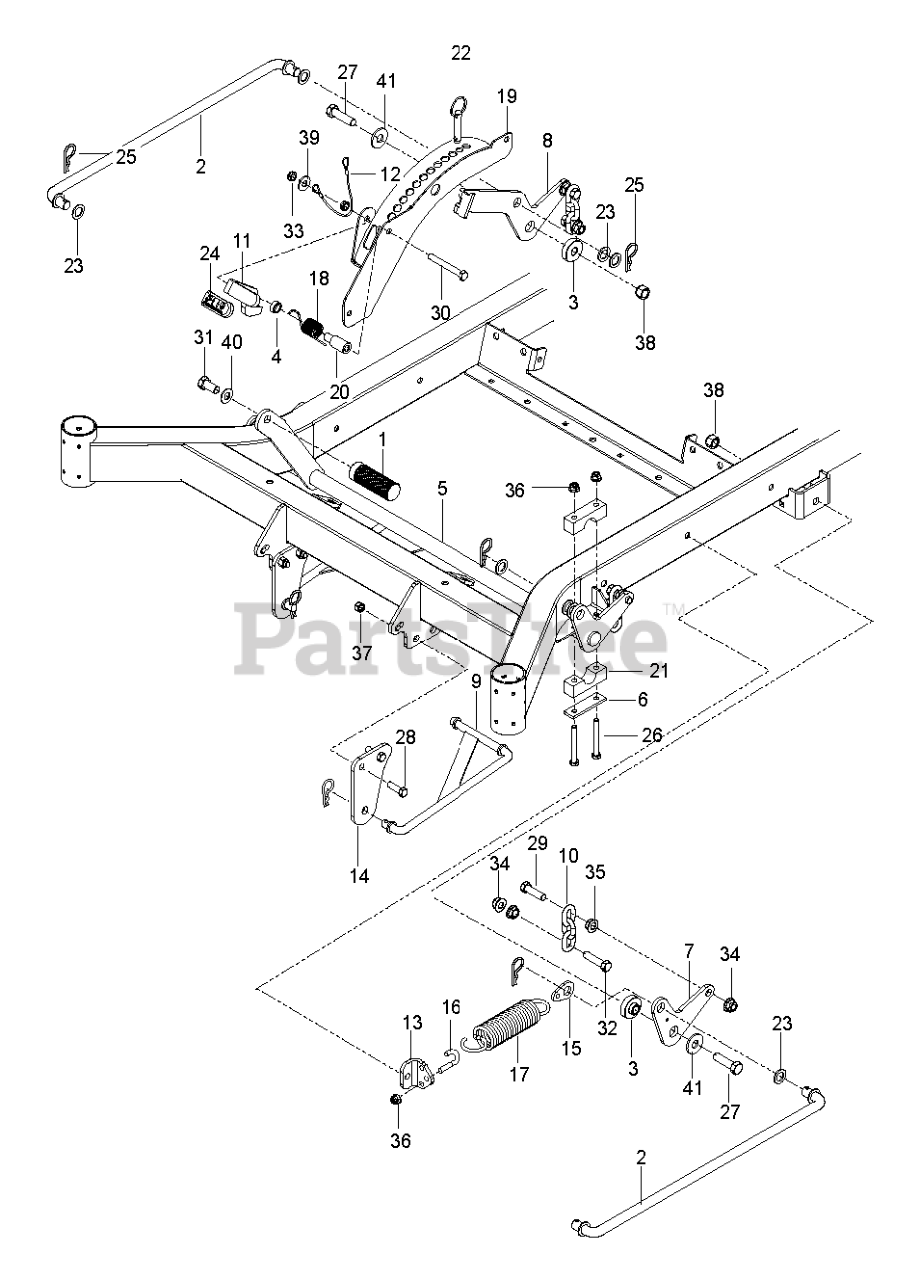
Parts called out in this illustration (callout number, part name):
5	LIFT.PNT.MZ.DECK.WELD.E-DIP
6	REINFORCEMENT.PLATEX431
7	BELLCRANK, RR, LIFT
8	BELLCRANK, RR, RT
9	STRUT LINKAGE
13	MOUNT, SPRING
14	MOUNT, STRUT
15	TAB, SPRING
19	Height Adjust
21	PILLOW BLOCK
24	GRIP, TRANSPORT-RELEASE
31	HHCS 1/2-13 X 1
32	HCS 7/16 - 14 X 1 3/4
34	Nuts
36	NUT HEXAGON FLANGE 5/16-18 ST
39	GSPW Washers
40	WASHER, 7/16 DISC SPRING
